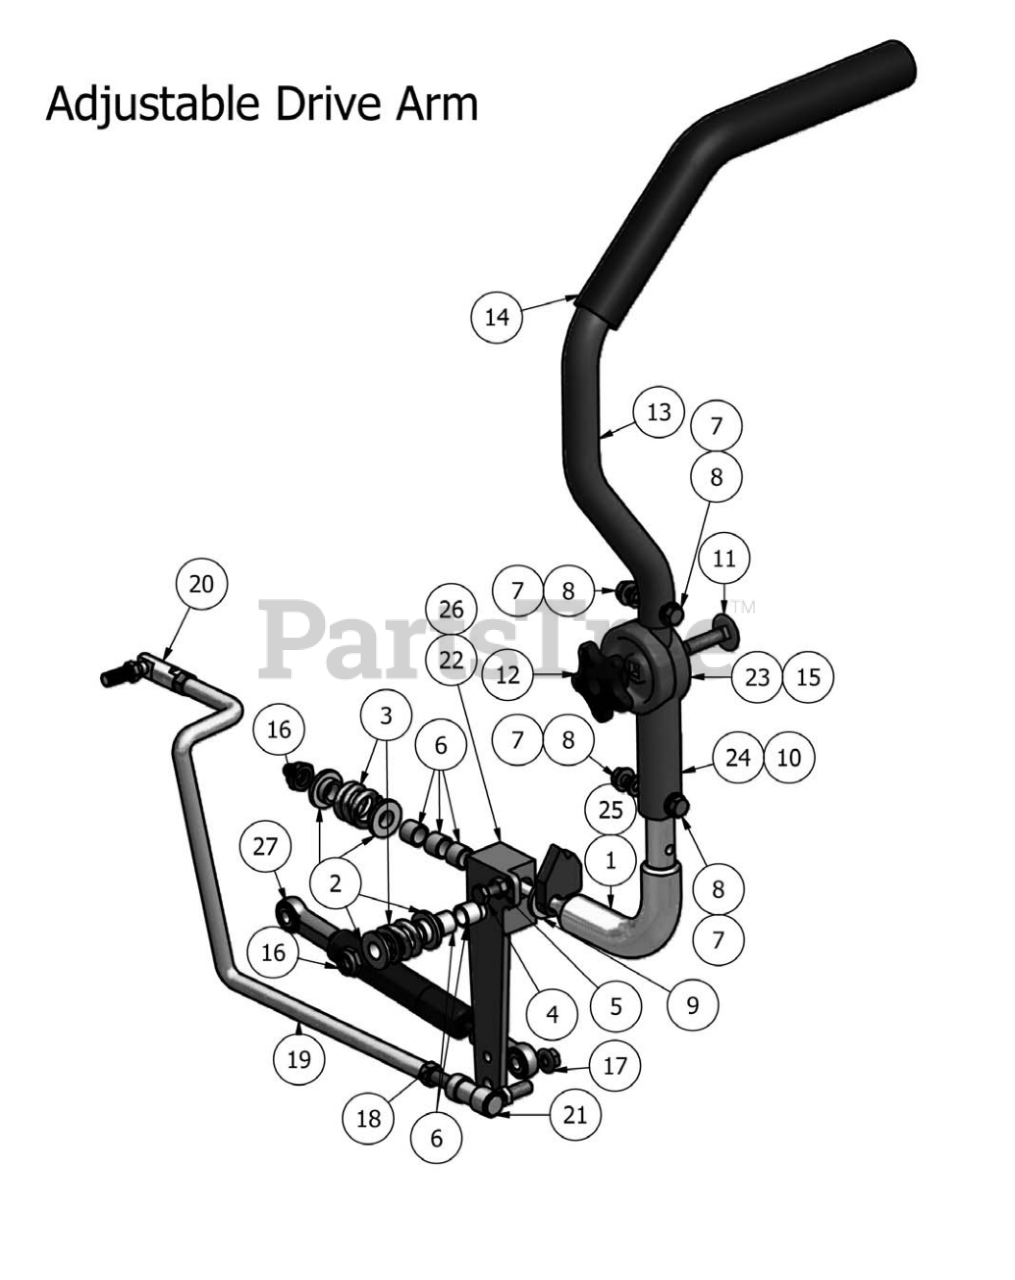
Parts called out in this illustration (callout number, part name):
1	Steering Arm Base-Right
2	.515 ID Nylon Shoulder Washer
3	Drive Lever Spring
4	5/16" x 3/4" Hex Bolt
6	.507 ID Nylon Bushing
7	5/16" Lock Washer
8	5/16" x 1/2" Flange Bolt
9	.635 ID Plastic Washer
10	Upper Adjuster for Steering Arm
11	3/8" x 1-1/4" Carriage Bolt
12	Black Knob for Adjustable Steering Arm
13	Upper Steering Arm Tubing-Adjustable
14	Black Steering Grips
15	Lower Adjuster for Steering Arm Left
16	1/2" Nylock Nut
17	5/16" Flange Nut
18	3/8" Fine Threaded Jam Nut
19	Push Rod Left & Right
20	3/8-24 Ball joint (female/male)
21	3/8-24 Quick Release Ball Joint
22	Drive Arm Lever Housing (Left)
23	Lower Adjuster for Steering Arm Right
24	Upper Adjuster for Steering Arm Right
25	Steering Arm Base-Left
26	Drive Arm Lever Housing (Right)
